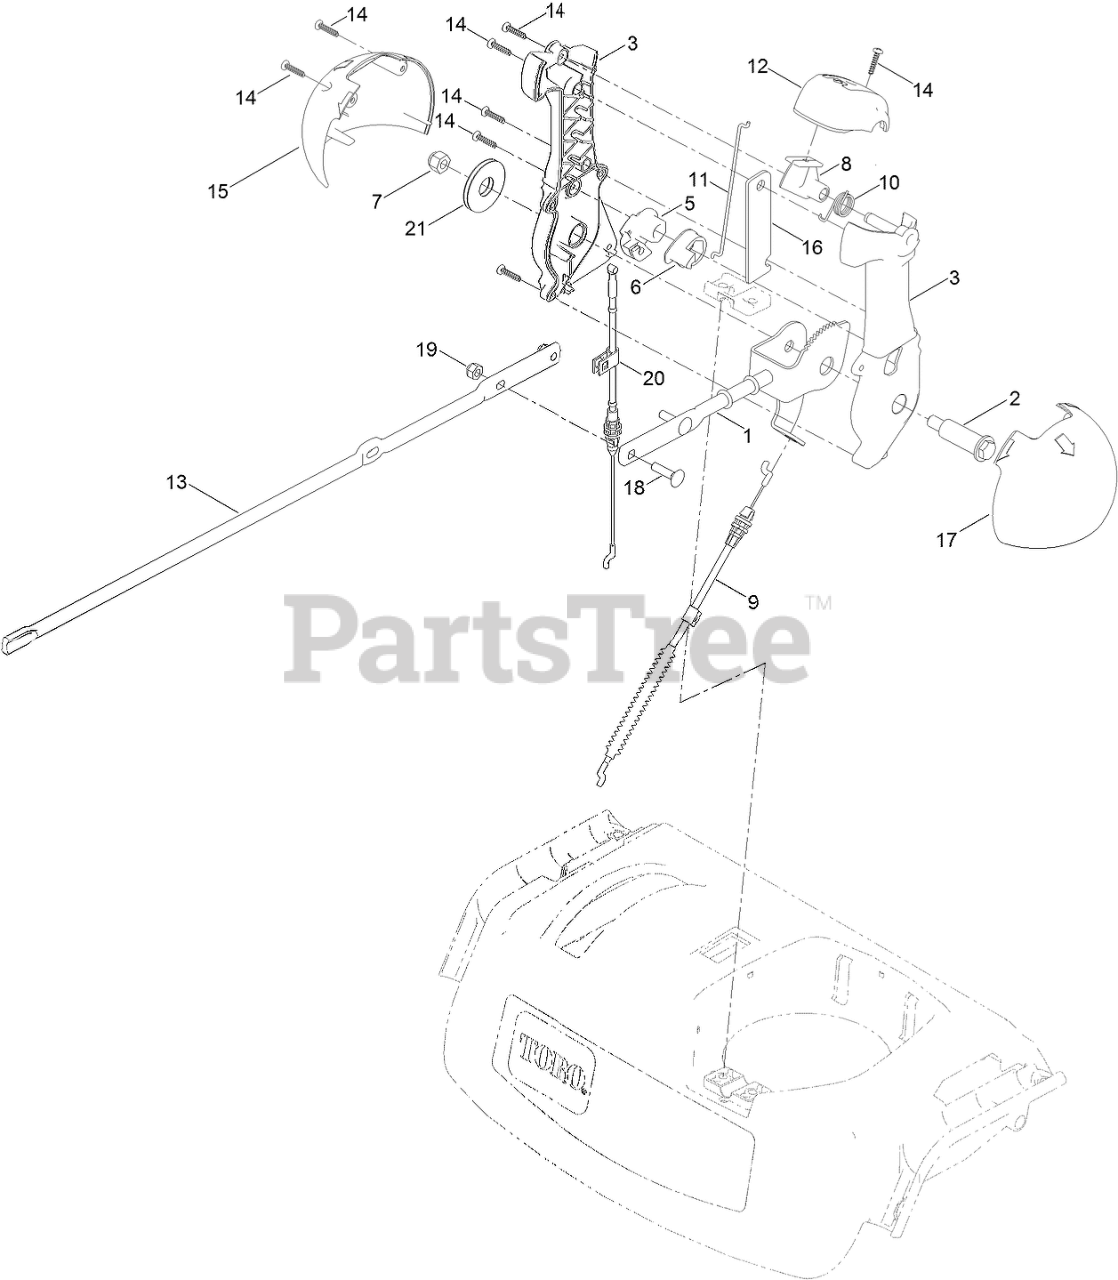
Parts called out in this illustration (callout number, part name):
1	ROD-CONTROL, CHUTE
2	SCREW-SHOULDER, HWH
3	CHUTE CONTROL LEVER ASM
5	LEVER-CABLE, DEFLECTOR
6	PAWL-LATCH
7	NUT-HEX
8	TRIGGER-LATCH
9	CABLE-CONTROL, DEFLECTOR
10	SPRING-TORSION
11	LINK-LATCH
12	CAP-LEVER
13	ROD-CHUTE, ROTATION
14	SCREW-PPH
15	GLOBE-QUICKSTICK, RH
16	PLATE-STIFFNER
17	GLOBE-QUICKSTICK, LH
18	BOLT-CARR
19	NUT-HEX
20	CABLE-RELEASE, CHUTE
21	WASHER-FRICTION, COMPOSITE
